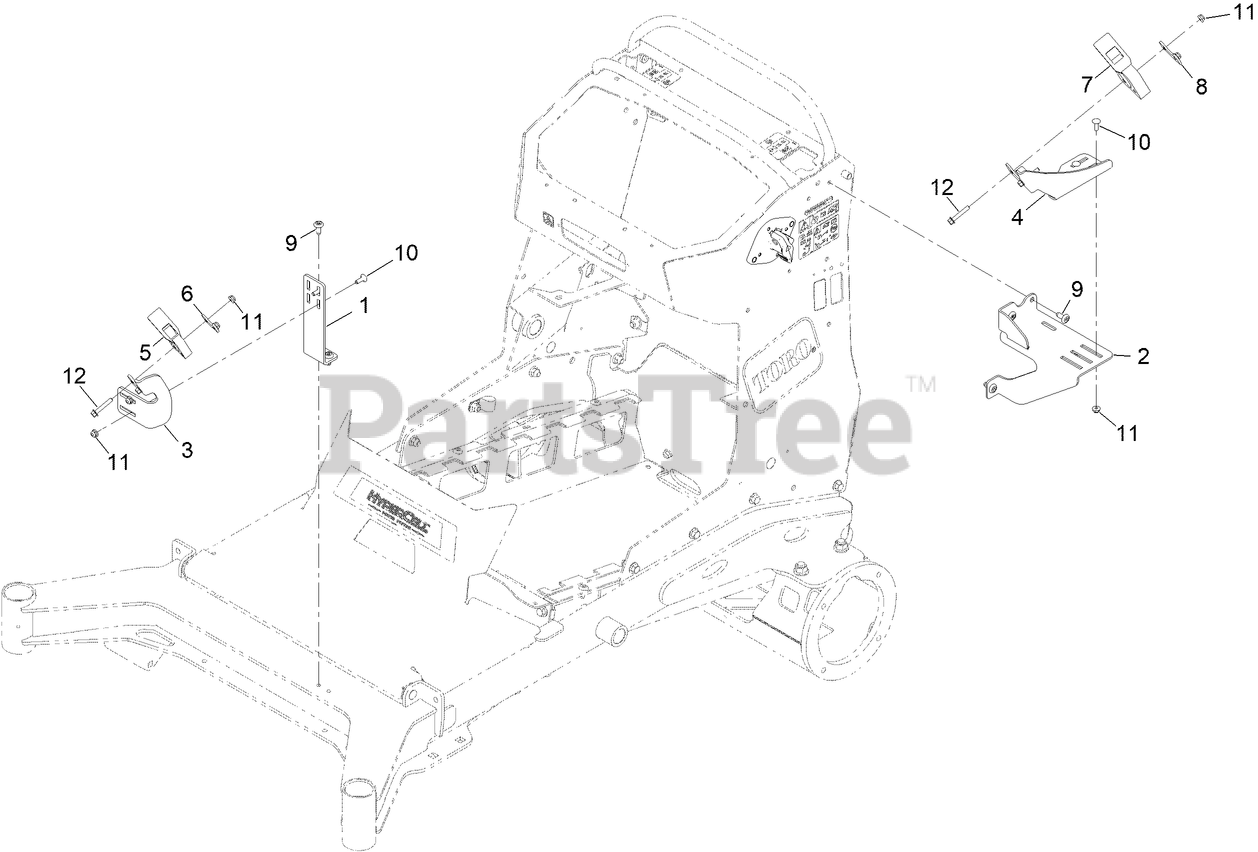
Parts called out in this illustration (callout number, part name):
1	BRACKET-MOUNT
2	BRACKET-MOUNT [RED]
3	PLATE-ADJUSTMENT
4	BRACKET-SLOT
5	CLAMP-QUICK FIST, MINI
6	PLATE, BACKER SMALL
7	CLAMP-QUICK FIST, ORIGINAL
8	PLATE, BACKER LARGE
10	BOLT-CARR
11	NUT-HF
12	SCREW-HHF
